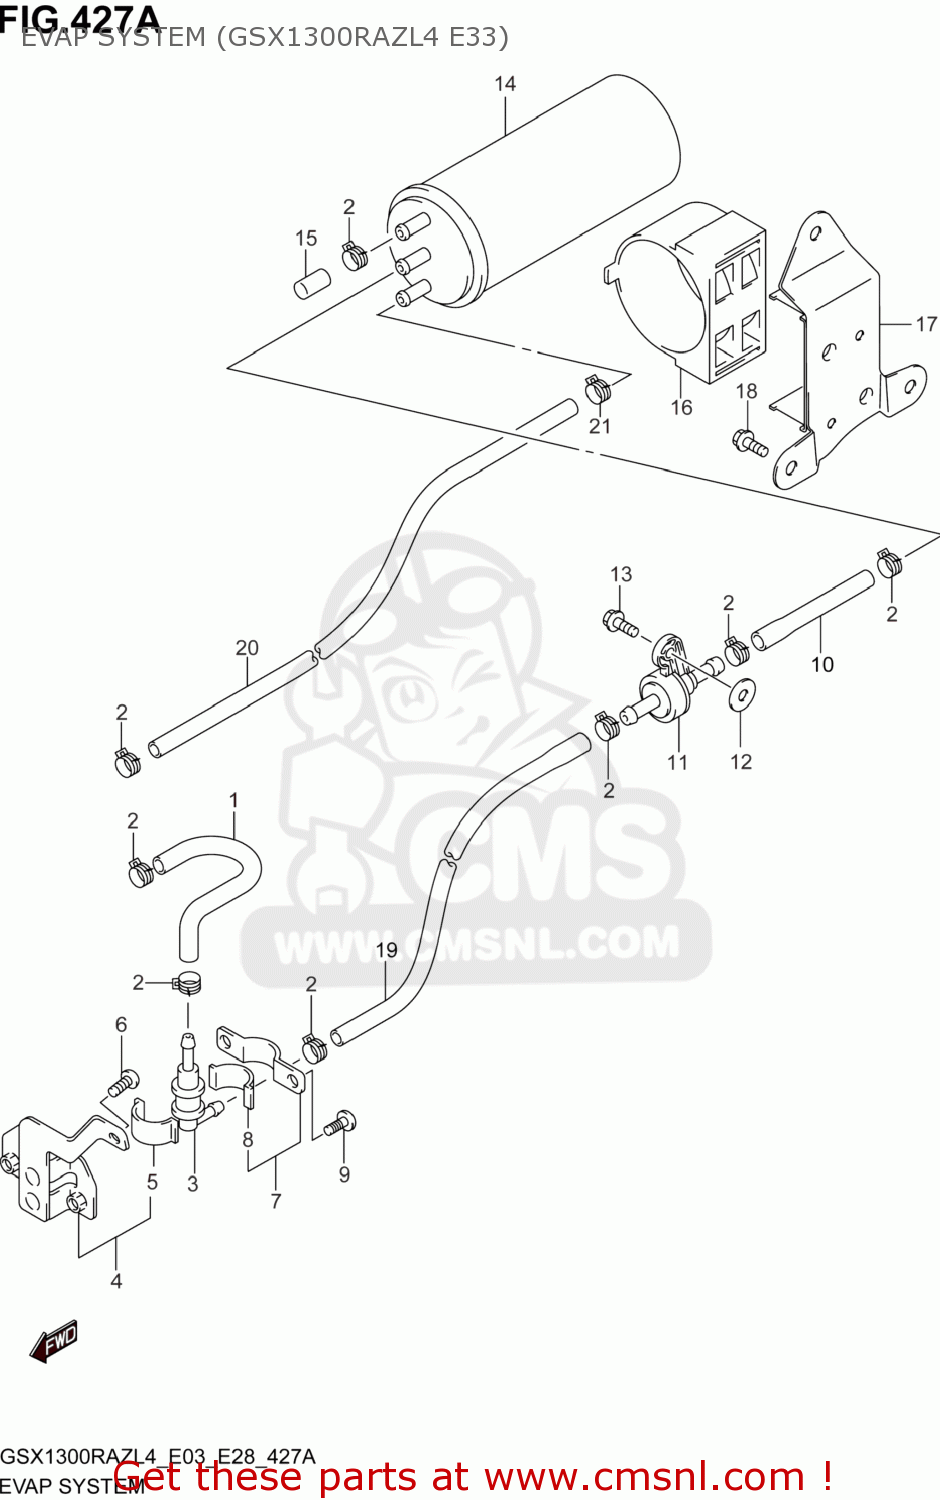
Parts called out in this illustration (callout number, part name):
1	HOSE,TANK & BREATHER VALVE
2	CLIP
3	VALVE,FUEL TANK BREATHER
4	PLATE,TANK BREATHER VALVE
5	CUSHION
6	SCREW
7	PLATE,FUEL TANK BREATHER NO.2
8	CUSHION
9	SCREW
10	HOSE,BRTHR VALVE & 2 WAY
11	VALVE,2 WAY & BREATHER VALVE
12	WASHER(6.5X20X1.2)
13	BOLT
14	CANISTER ASSY,CHARCOAL
15	CAP
16	CUSHION,CANISTER
17	BRACKET,CANISTER
18	BOLT
19	HOSE,2 WAY & CSTR
20	HOSE
21	CLIP
